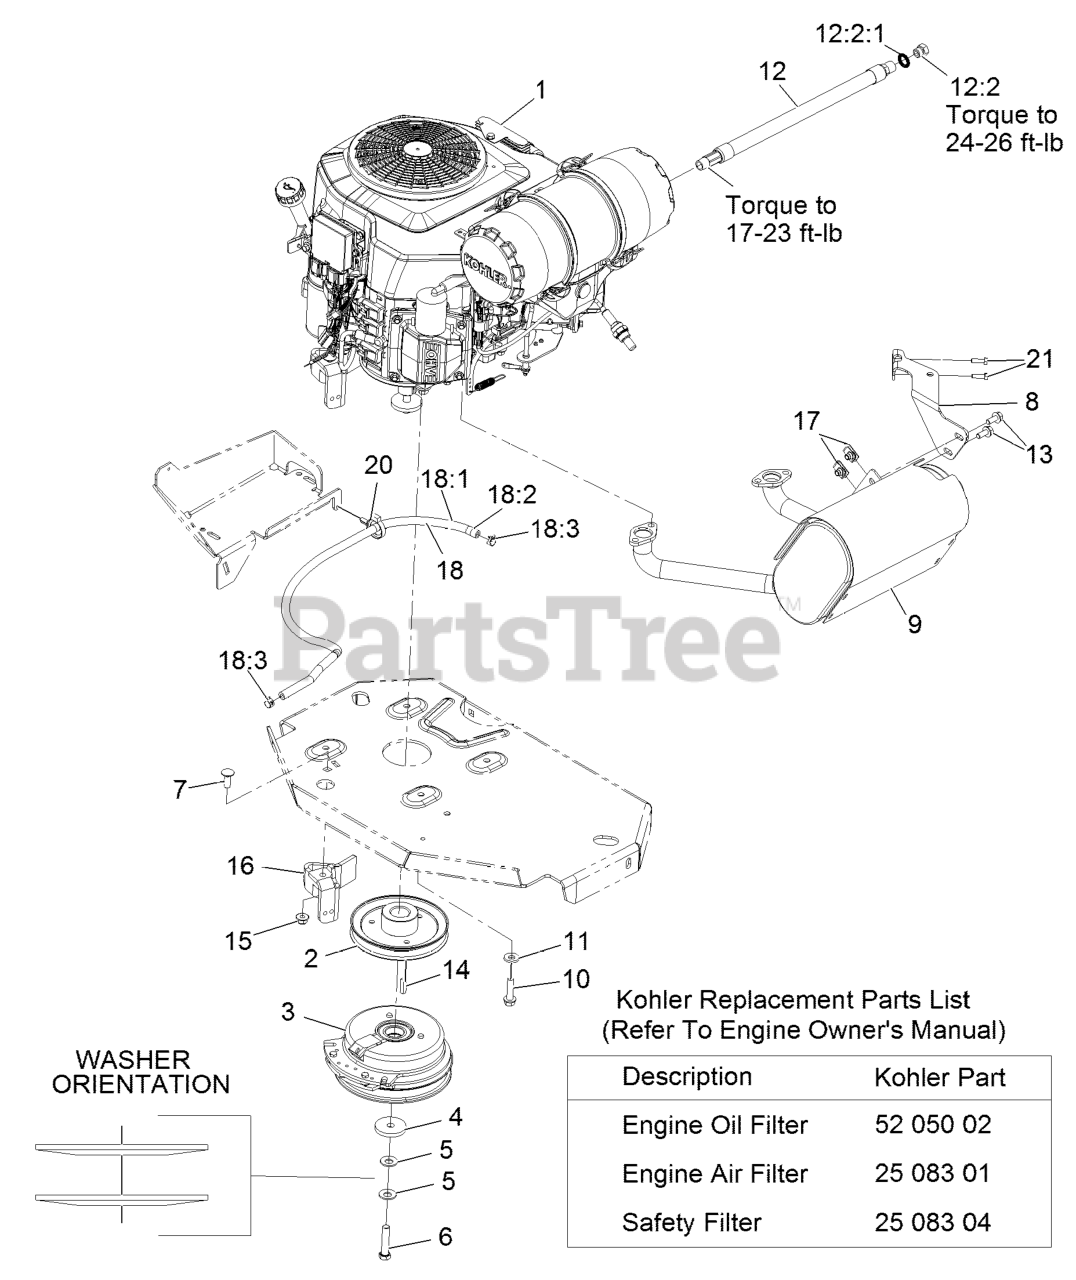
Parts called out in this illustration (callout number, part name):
1	Engine-Kohler
2	SHEAVE
3	CLUTCH KIT
4	WASHER-CLUTCH
5	WASHER-SPRING
6	SCREW-HH W/LOCTITE
7	SCREW-CARR
8	MUFFLER BRACKET KIT
10	SCREW-HWH
11	WASHER-BELLEVILLE
12	OIL DRAIN HOSE ASM
12:2	PLUG-HH
12:2:1	O-RING
13	SCREW-HHF
15	NUT-HF, NI
16	CLUTCH-ANCHOR
18	FUEL LINE ASM
18:1	HOSE-FUEL
18:2	SLEEVE-THERMAL
18:3	CLAMP-HOSE
20	CLAMP-HOSE
21	SCREW-HH M6-1 X 20Mm W/Patch
